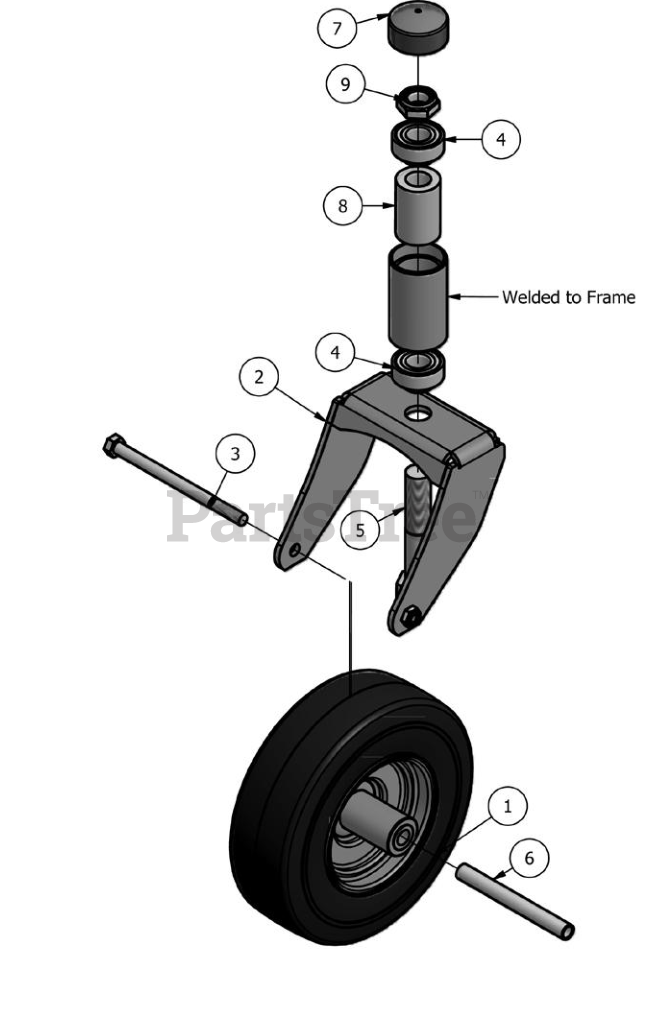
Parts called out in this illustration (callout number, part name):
1	11 x 4.00 5 Front tire (Smooth) & Wheel Assembly
2	Front Fork
3	1/2 x 7 Hex Bolt Grade 5
4	Mini Z Bearing
5	1-14 x 5 Hex Bolt Grade 8 Zinc Yellow
6	Front Wheel Spanner
7	Rubber Bearing Cap
8	MZ Caster Bearing Spacer
9	1-14 Nylock Jam Nut
10	1/2-20 Nylon Insert Jam Locknut Zinc Orange Zinc
11	Wheel Bearing MZ
12	11 x 4.00 5 Tire Only MZ
13	Front Wheel Only MZ
